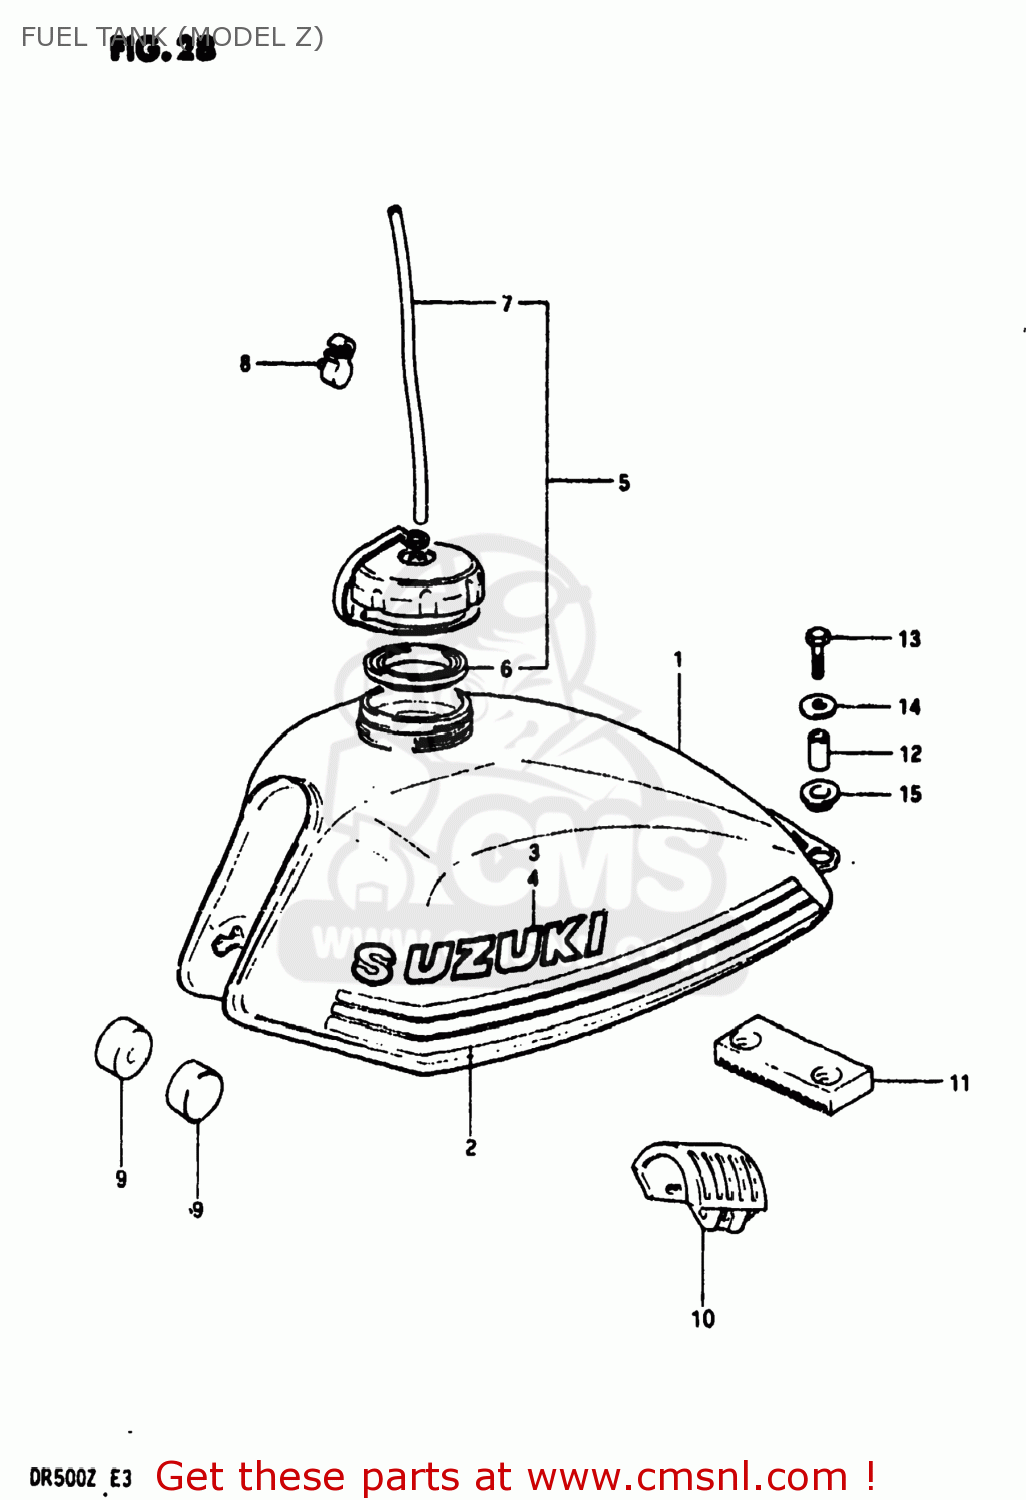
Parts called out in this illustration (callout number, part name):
1	TANK ASSEMBLY,FUEL
2	TAPE SET,FUEL TANK
3	EMBLEM,FUEL TANK,RIGHT
4	EMBLEM
5	CAP SET,FUEL TANK
6	GASKET,FUEL TANK CAP (NAS)
7	HOSE
8	CLAMP,FUEL TANK BREATHER HOSE
9	CUSHION
10	CUSHION,FUEL TANK UPR FR
11	CUSHION,FUEL TANK,REAR
12	SPACER (6.5X10.5X29)
13	BOLT 6X40
14	WASHER (6.5X24X1.6)
15	CUSHION
